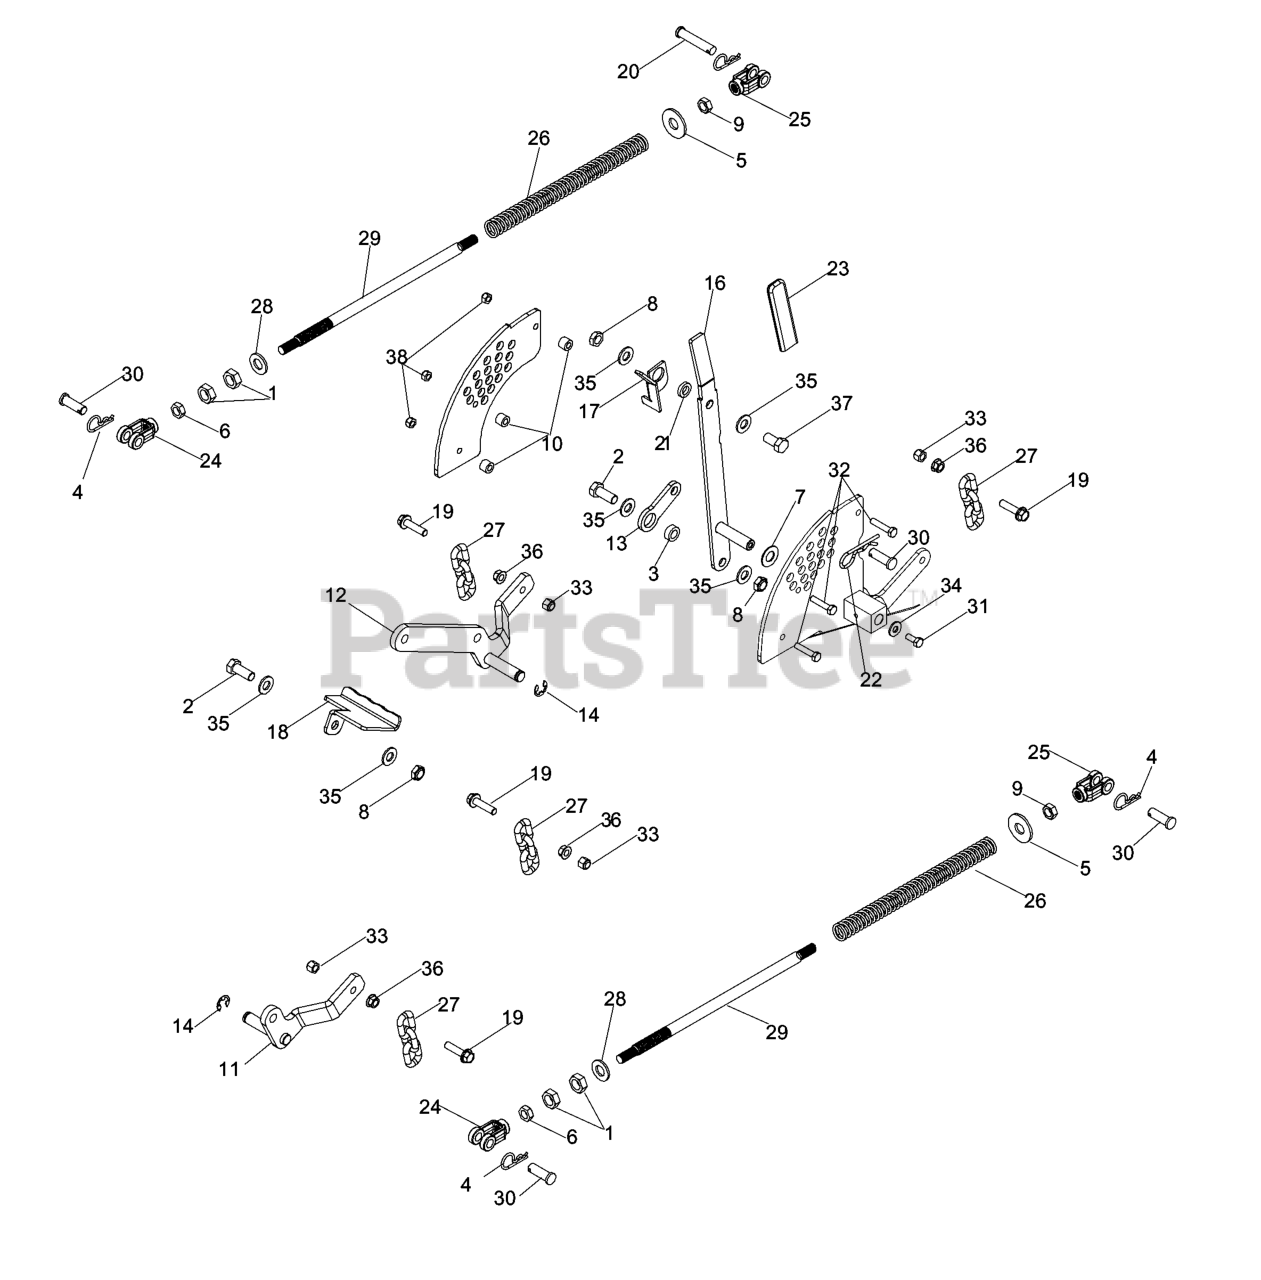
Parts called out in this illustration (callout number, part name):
1	NUT JAM 5/8-11 HEX
2	HCS 1/2-13 X 1-1/4
3	BLADE ADAPTOR
4	PIN, COTTER 1 3/4
5	5/8 STD FLATWASHER
6	1/2-20 HEX JAM NUT
7	WASHER 5/8IDX.063 TK
8	NUT 1/2-13 HEX JM NYL
9	1/2-20 LH HEX JAM NUT
11	WLDT LIFT ARM LH
12	WLDT LIFT ARM RH
13	LINK LIFT HANDLE BLUE
14	RETAINING RING 5/8
15	OUTER QUADRANT(PLATED)
16	LIFT HANDLE WLDT.
17	LIFT LATCH
18	FOOT PEDAL
19	3/8-16 X 1.5 FLG HHB
20	CLEVIS PIN 2-1/2
22	5/32 X 3.0 HAIR PIN COTT
23	GRIP BRAKE HANDLE
24	CLEVIS FEMALE-RH
25	CLEVIS FEMALE-LH
26	LIFT SPRING
28	WASHER PLATED
29	TIE BAR
30	CLEVIS PIN 1/2X1-1/2` L
31	HCS 5/16C X 3/4
32	CAPSCREW 5/16 X 1/1/2 HEX HEAD
33	NUT 3/8-16 NYLOC
34	FLAT WASHER 5/16 SAE
35	WASHER 1/2" FLAT
36	NUT 3/8C WHIZ
37	HHCS 1/2-13 X 1
38	NUT 5/16 NYLOC
